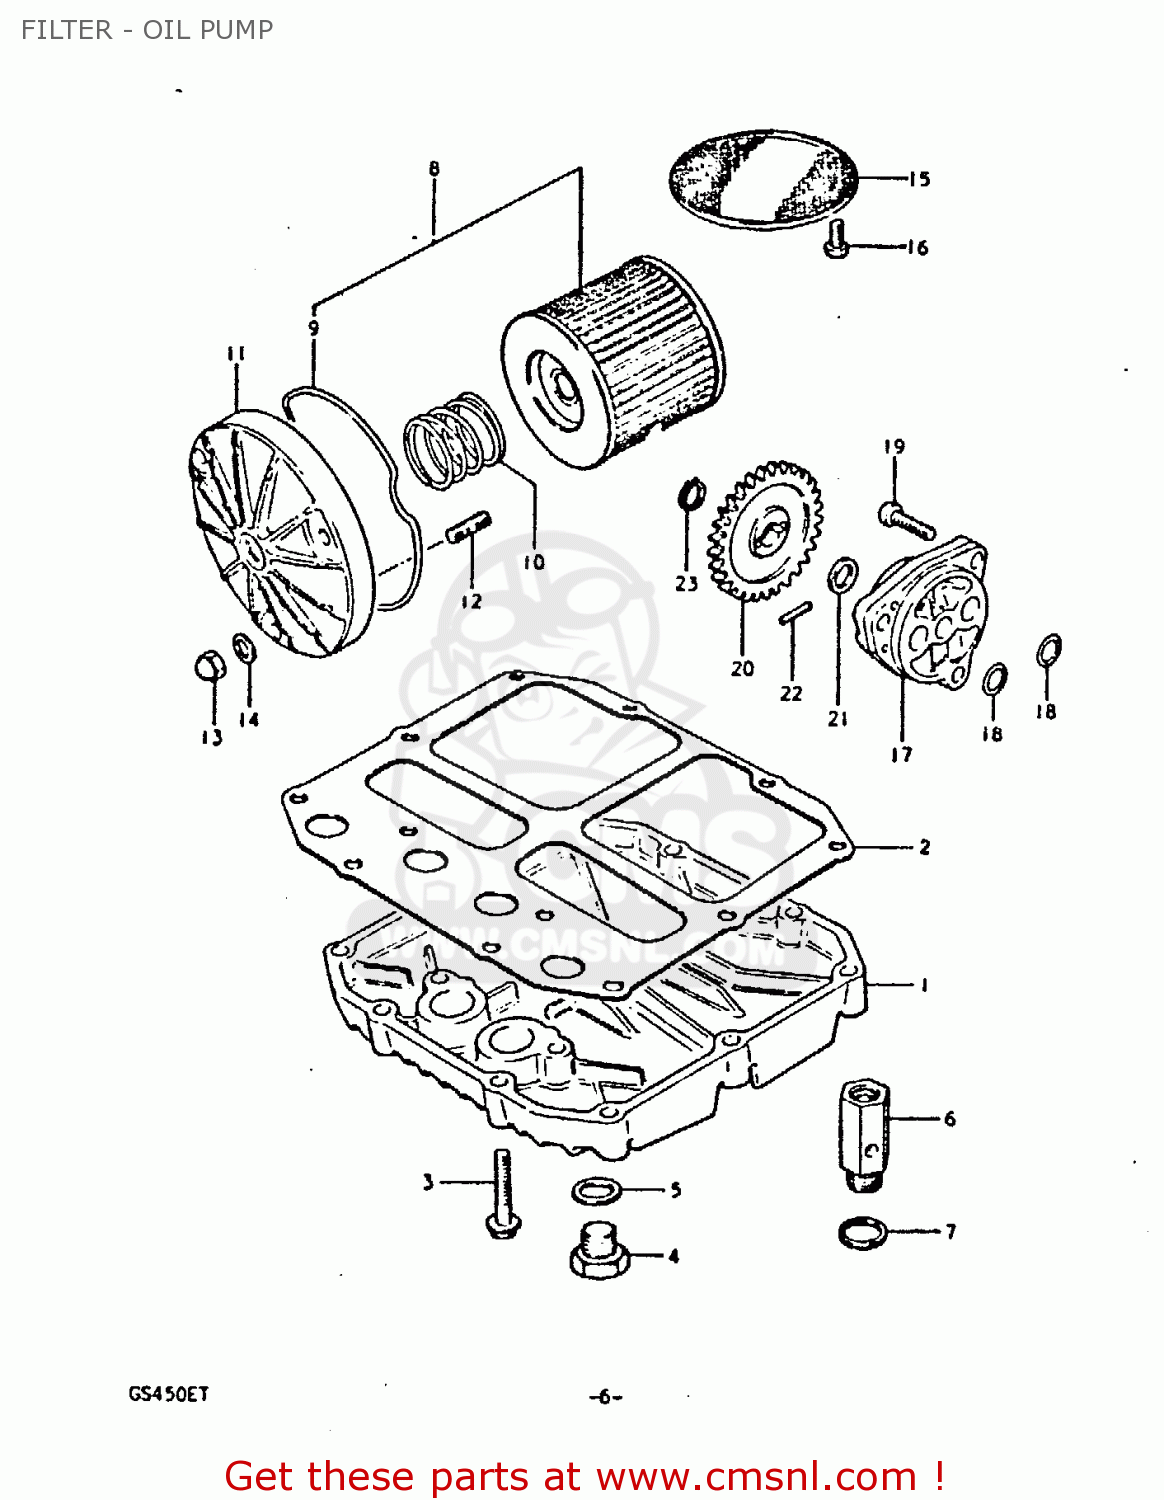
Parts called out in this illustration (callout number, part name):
1	PAN,OIL
2	GASKET,OIL PAN (MCA)
3	BOLT
4	PLUG
5	GASKET(14X19.2X2) (NAS)
6	REGULATOR ASSEMBLY,ENGINE
7	WASHER
8	ENGINE OIL FILTER SET
9	O RING,OIL FILTER CHAMBER CAP
10	SPRING
11	CAP,OIL FILTER
12	STUD 6X20
13	NUT
14	WASHER
15	STRAINER,ENGINE OIL
16	SCREW 6X12
17	PUMP ASSY,ENGINE OIL
18	O RING(D:1.9,ID:13)
19	SCREW
20	GEAR,OIL PUMP DRIVEN
21	SHIM
22	PIN(4X15.8)
23	CIRCLIP
